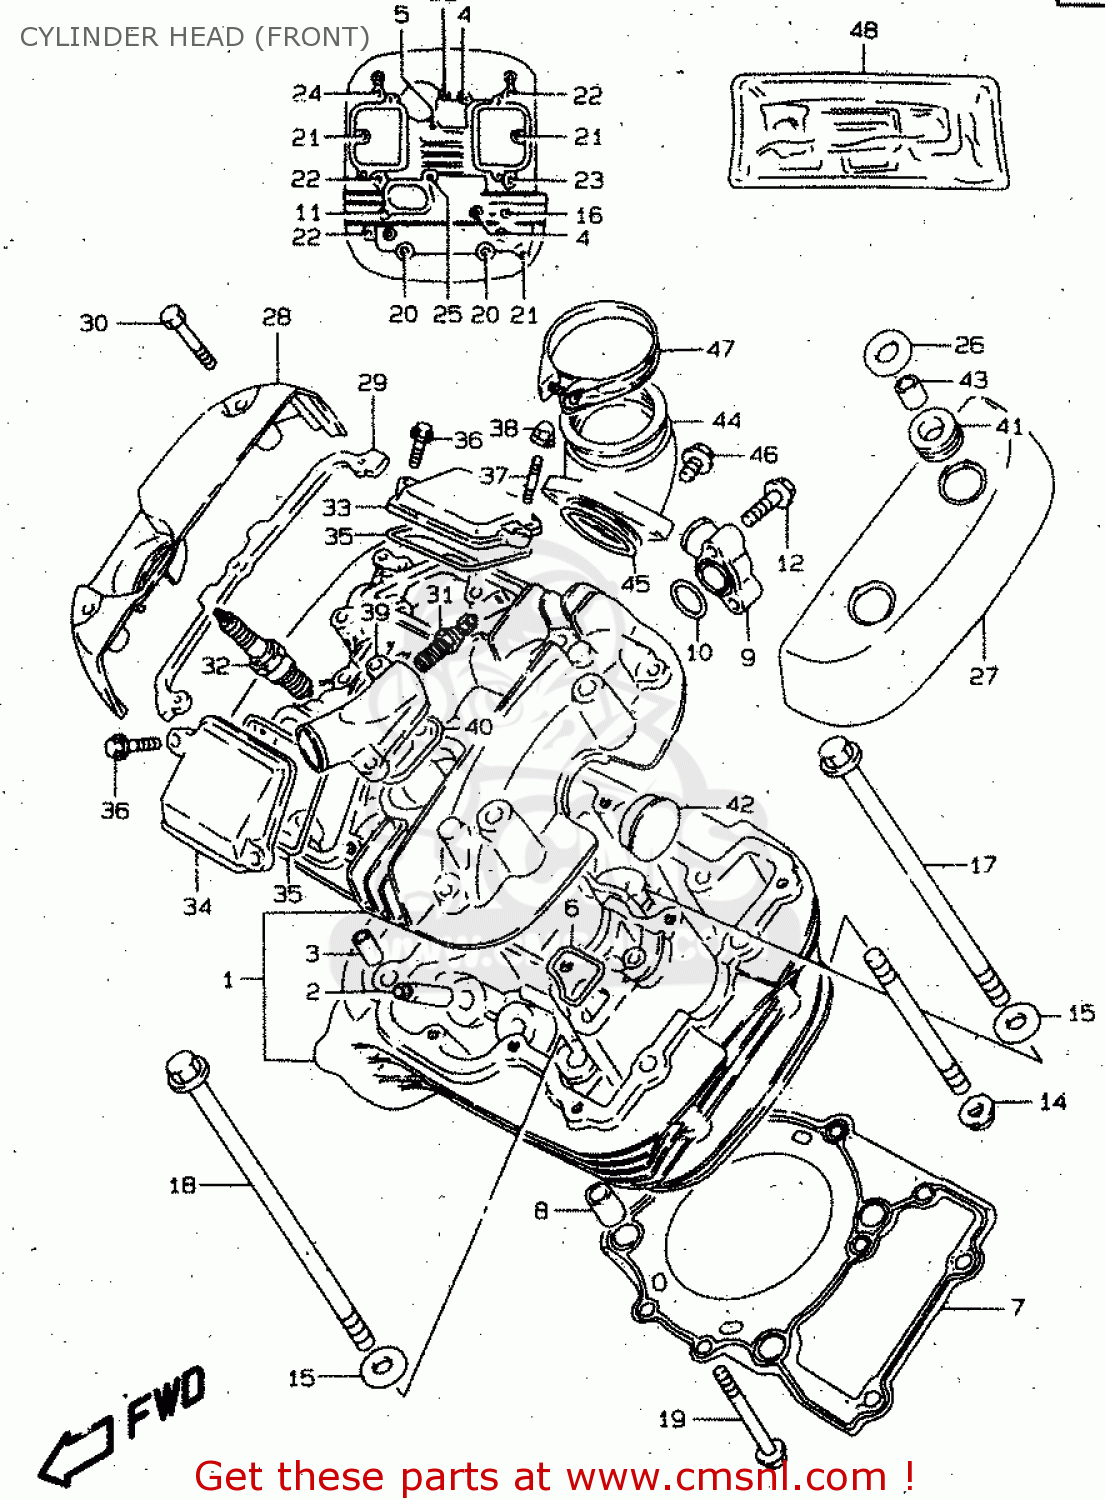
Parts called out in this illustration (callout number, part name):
1	HEAD ASSY,CYLINDER FR
2	GUIDE,VALVE
3	PIN(8.4X11X14)
4	BOLT(6X50)
5	BOLT(6X55)
6	GASKET,CYLINDER HEAD WATER (NAS)
7	GASKET,CYLINDER HEAD FR (NAS)
8	PIN
9	UNION,CYLINDER HEAD WATER
10	O RING(D:2.4,ID:17.8)
11	BOLT
12	SCREW
13	BOLT,STUD
14	NUT
15	WASHER (10.5X22X2.3)
16	BOLT(8X140)
17	BOLT(10X155)
18	BOLT(10X165)
19	BOLT
20	BOLT(8X245)
21	BOLT
22	BOLT
23	BOLT
24	BOLT
25	BOLT(6X55)
26	WASHER(8.5X24X1.6)
27	CAP,CYLINDER HEAD COVER FR,L
28	CAP,CYLINDER HEAD COVER FR,R
29	CUSHION,FR,R CAP
30	BOLT
31	GAUGE ASSY,WATER TEMP
32	PLUG,SPARK(DPR8EA-9)
33	CAP,INSPECTION INTAKE
34	CAP,INSPECTION EXHAUST
35	GASKET,INSPECTION CAP (NAS)
36	BOLT
37	STUD 6X16
38	NUT
39	UNION,WATER OUTLET
40	GASKET,WATER OUTLET UNION (NAS)
41	CUSHION
42	PLUG(OD:30)
43	BUSH
44	PIPE,INTAKE
45	O RING(D:2.4,ID:39.7)
46	BOLT
47	CLAMP
48	GASKET SET
